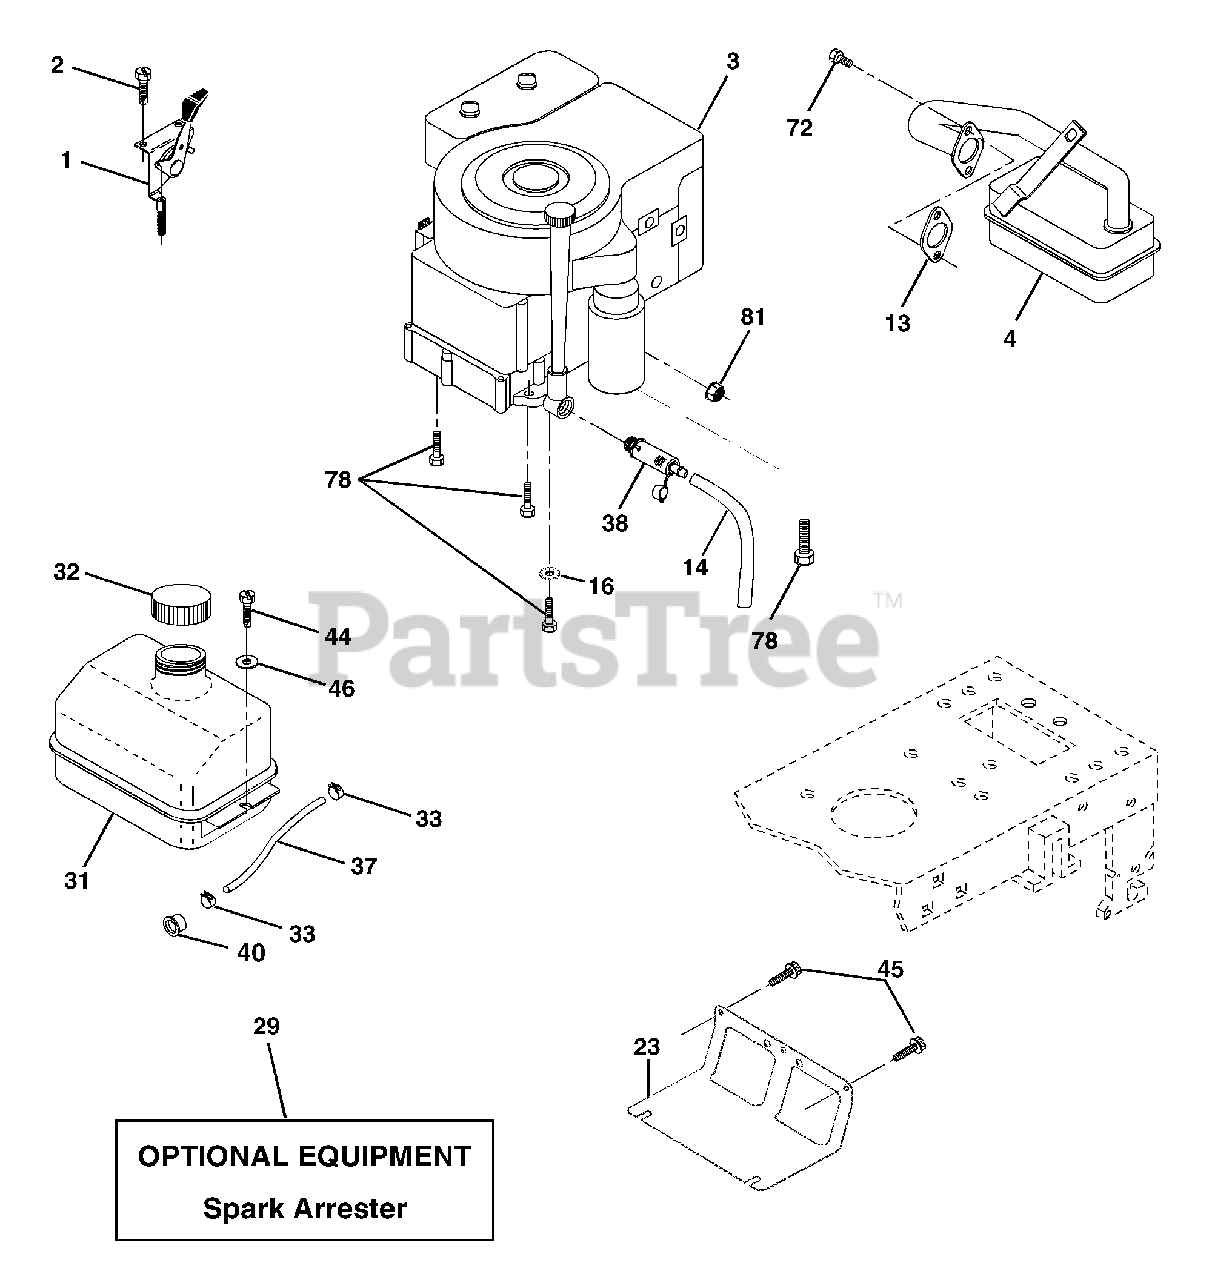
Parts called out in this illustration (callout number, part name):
1	Control Th/ch
2	Screw Hex Thd Cut 1/4-20 x 1/2
4	Muffler
13	Gasket Eng 1 313 Id Tin Plated
14	Tube Drain Oil Easy
16	Washer Lock Ext Tooth 3/8
23	Shield Browning
29	Kit Spark Arrestor (Flat Scrn)
31	Tank Fuel Front 1 25
32	Cap Asm Fuel
33	Clamp Hose Blk
37	Line Fuel 20"
38	Plug Drain Oil Easy
40	Bushing Snap Nyl Blk Fuel Line
44	Screw Hexwsh Thdrol 1/4-20 x 3/4
45	Screw Hex Wsh Thdrol 3/8-16
46	Washer 9/32 x 7/8 x 16 ga
72	Screw Socket Head 5/16-18 x 1
78	Screw 3/8-16 x 1-1/4
81	Nut Keps Hex 1/4-20 UNC
